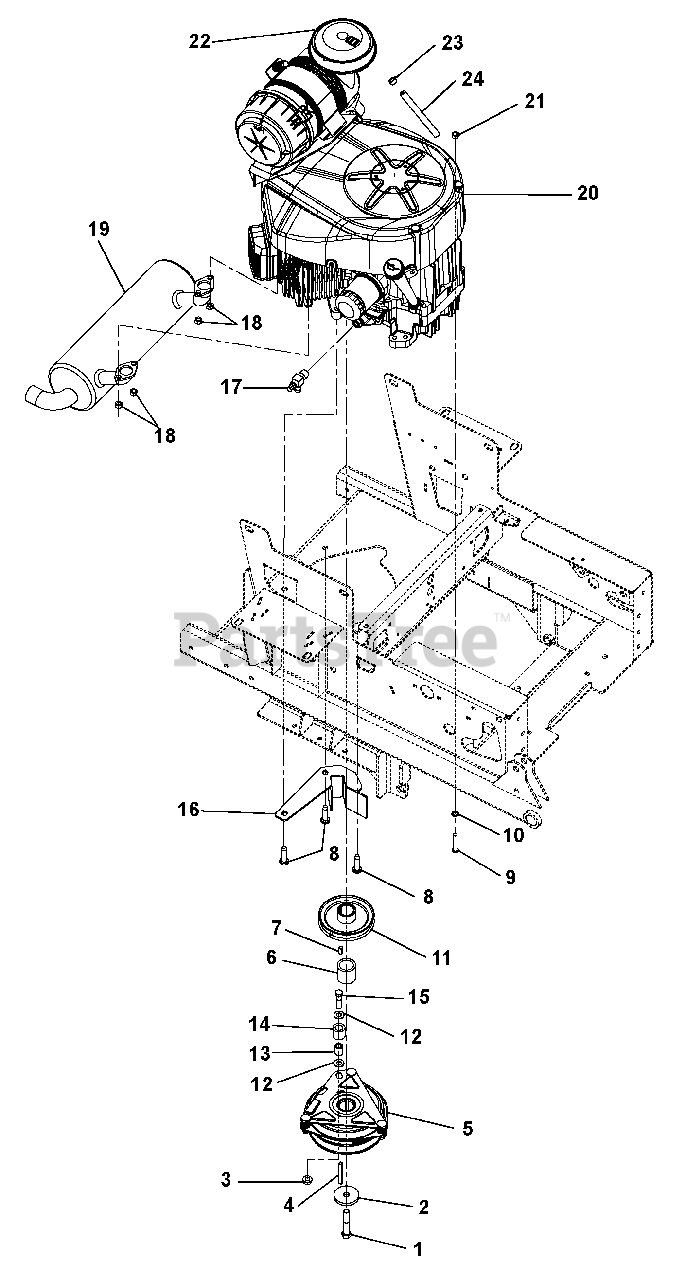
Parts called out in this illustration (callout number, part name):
1	Bolt, Hex .44-20 x 2.50 Grade 5
2	Washer, Flat-Steel .469 x 2.00 x .25
3	Nut, Locking-Top-Flange .38-16
4	Key, .25 x .25 x 2.25
5	Clutch, Ogura GT2.5-FE02
6	Spacer, 1.125 x 1.50 x 1.40
7	Key, Square .25 x .625 x .25 SAE 8630 OR SAE 1035
8	Screw, Tapping Hex Washer Head .38-16 x 1.50
9	Bolt, Hex .31-18 x 1.50 Grade 5
10	Washer, Locking-EXT.326 x .599 x .03
11	Sheave, 4.831 x 1.127
12	Washer, Flat-Steel .406 x .812 x .065
13	Bushing, S.407 x .625 x .813 Steel
14	Bumper, Rubber .62 x 1.0 x .88 LG Engine
15	Bolt, Hex .38-16 x 1.50 Grade 5
16	100I Clutch Stop Weldment
17	Drain, .50 Oil
18	Nut, Locking-Top M8-1.25
19	Muffler, Kawasaki
20	Engine, 23HP Kawasaki (060, 061)
21	Nut, Locking-Center .31-18
22	Cap, 2" Air Cleaner Intake
23	Clamp, Fuel Line
24	Hose, .25 Low-PERM Bulk Gas
